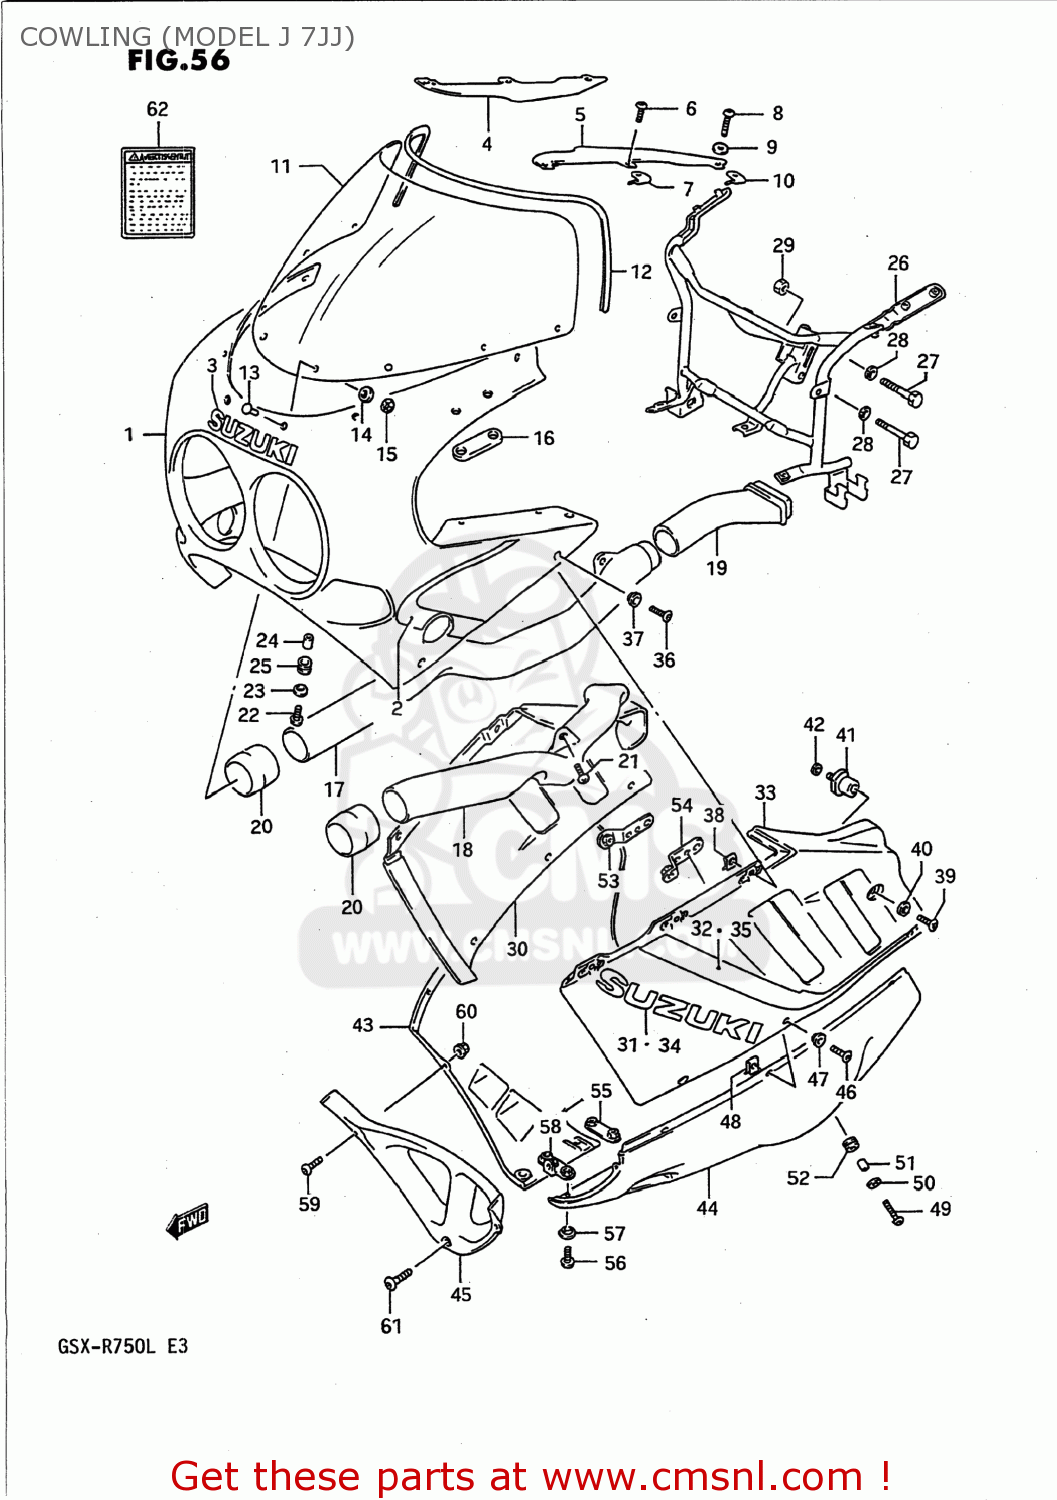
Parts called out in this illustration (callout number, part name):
1	BODY ASSEMBLY,COWLING
2	TAPE SET,COWLING,UPPER
3	EMBLEM,COWLING,UPPER (W)
4	PANEL,COWLING UPPER,RIGHT
5	COVER,COWLING,LEFT
6	SCREW(5X10)
7	NUT
8	SCREW(5X14)
9	WASHER(5.2X11X1)
10	NUT
11	WINDSCREEN
12	MOLDING,WINDSCREEN
13	PIN,WINDSCREEN
14	CUSHION
15	NUT
16	CUSHION,RR VIEW MIRRORR
17	PIPE,AIR INTAKE,FRONT
18	PIPE,AIR INTAKE,FRONT
19	PIPE,AIR INTAKE RR,R
20	JOINT,AIR INTAKE
21	SCREW
22	SCREW(6X20)
23	WASHER(6.5X18X1)
24	SPACER
25	CUSHION
26	BRACE,COWLING
27	BOLT
28	WASHER,LOCK,8.
29	NUT ,8MM
30	COVER COMP,COWLING SIDE,RIGHT
31	EMBLEM,COWLING SIDE (RED)
32	TAPE,COWLING SIDE STRIPE
33	COVER COMP,COWLING SIDE,LEFT
34	EMBLEM,COWLING SIDE (RED)
35	TAPE,COWLING SIDE STRIPE
36	SCREW(5X18)
37	WASHER(5.2X14X1.5)
38	NUT,HEADLAMP HOUSING,UPPER
39	SCREW(6X12)
40	WASHER(6.3X16X1.5)
41	CUSHION,COWLING
42	WASHER,LOCK
43	COWLING COMP,UNDER,RIGHT
44	COWLING COMP,UNDER,LEFT
45	COWLING,UNDER,CENTER
46	SCREW(5X18)
47	WASHER(5.2X14X1.5)
48	NUT,HEADLAMP HOUSING,UPPER
49	SCREW(6X20)
50	WASHER(6.5X18X1)
51	SPACER
52	CUSHION
53	BRACKET
54	BRACE,COWLING UNDER,LH
55	BRACE,COWLING LWR COVER RR
56	SCREW(6X16)
57	WASHER(6.3X16X1.5)
58	BRACE,COWLING LWR COVER
59	SCREW(5X14)
60	NUT
61	SCREW(6X16)
62	LABEL (WARNING SCREEN)
